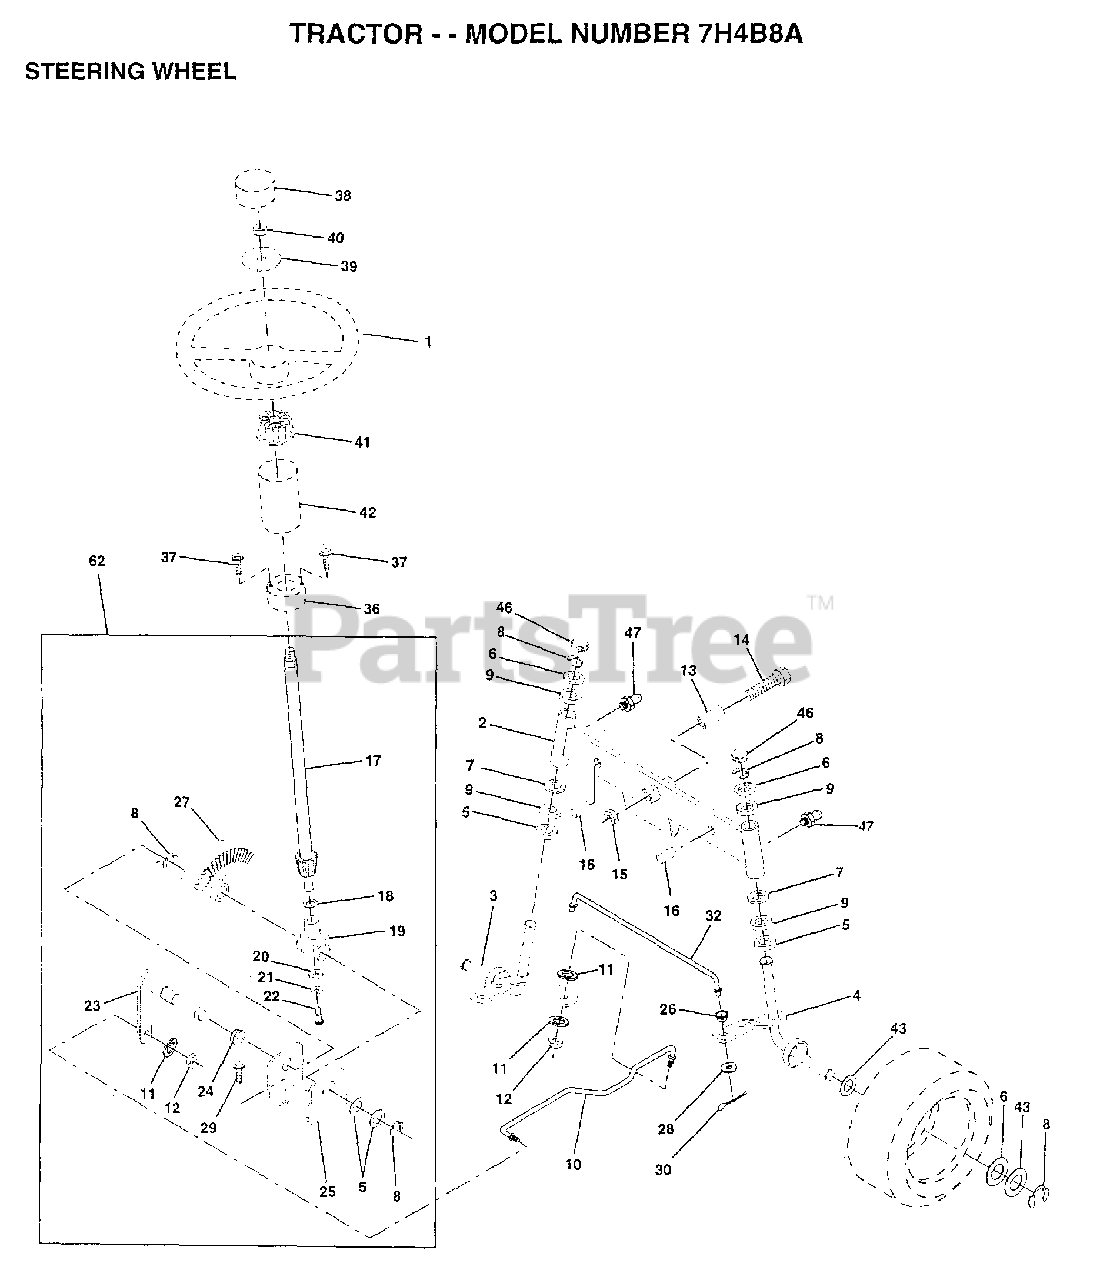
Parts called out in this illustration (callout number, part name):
2	AXLE ASM FRONT
3	SPINDLE LH
4	SPINDLE RH
5	WASHER .T
6	WASHER
7	WASHER
8	RING
9	COL. SRTG. BEAR.
11	LOCKWASHER
13	BEARING
15	"NUT-LOC,FLANGE LT"
16	AXLE PIN
17	SHAFT ASM
18	THRUST WASHER
19	SUPPORT.SHAFT
21	LOCKWASHER
22	SCREW.SCKTHD.CAP
24	NYLINER T
25	"BRKT,STEERING"
26	BUSHING.DRAGLINK
27	GEAR SECTOR
28	WASHER
29	SCREW
30	COTTER PIN
32	TIE ROD
37	"SCREW-TT,10-32 FL"
38	ST WHL INSERT CAP
39	WASHER T
40	GRIPCO NUT
41	ADAPTER-WHEEL LT
42	"TUBE, STR SHAFT"
43	WASHER
46	CAP
47	ZERK M
